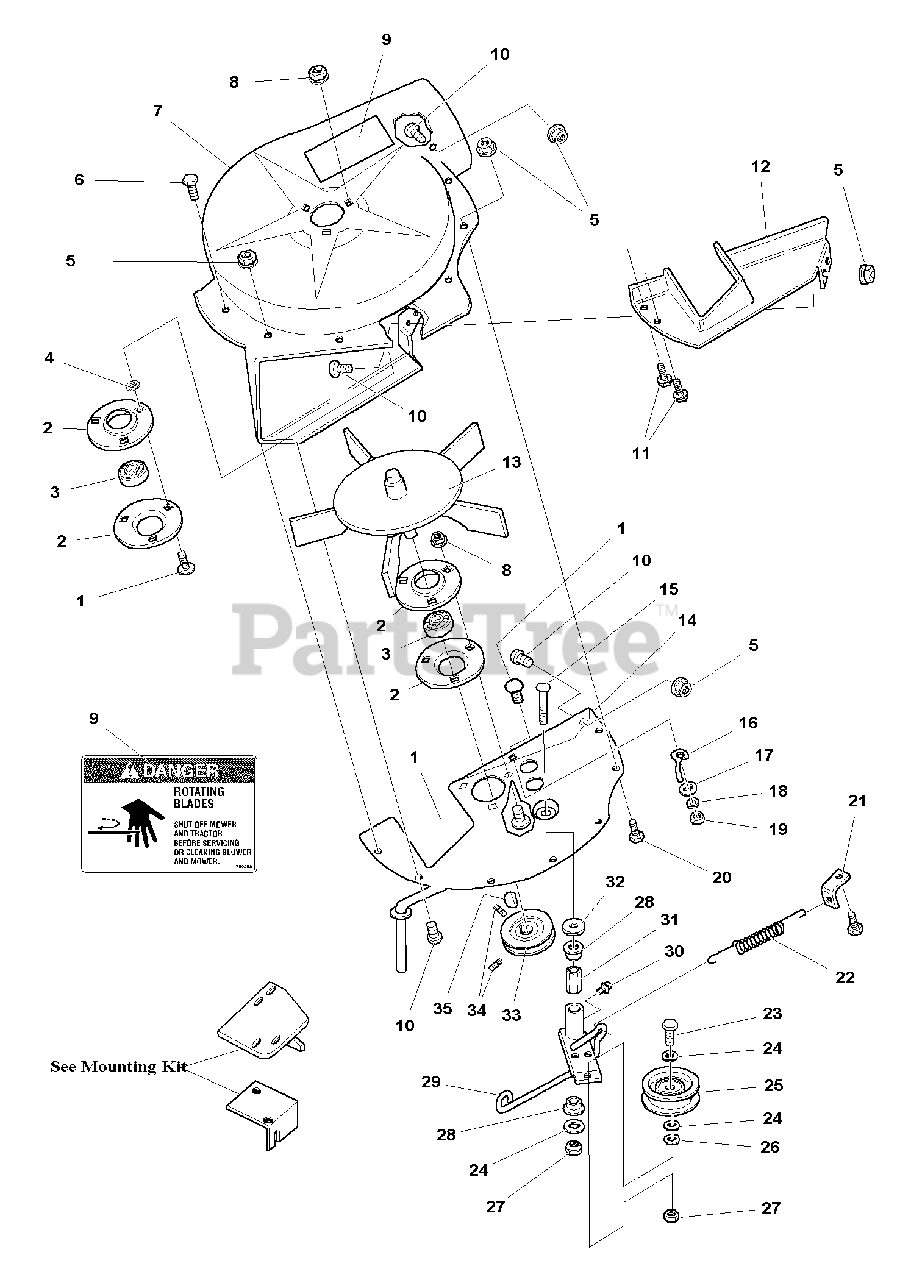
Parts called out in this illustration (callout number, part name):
1	CARRIAGE BOLT, 5/16-18 x 3/4
2	RETAINER, Bearing
4	PUSH NUT, 3/8
5	NUT, Hex, Flange Lock, 1/4-20
6	CAPSCREW, Hex, Taptite, 1/4-20 x 1/2
7	FAN HOUSING (Includes Decal, #9)
8	NUT, Flange, Whizlock, 5/16-18
9	DECAL, Danger, Blower
10	CARRIAGE BOLT, 1/4-20 x 3/4
11	SCREW, Wsh. Hd., 1/4-18 x 5/8
12	COVER, Bottom
13	FAN ASSY., 5 Blade
14	PLATE ASSY.
15	CARRIAGE BOLT, 3/8-16 x 2-1/4
17	WASHER, Flat
18	WASHER, Spring Lock, 5/16
19	NUT, Hex, 5/16
20	CAPSCREW, 1/4-20 x 5/8
21	BRACKET, Anchor, Spring
22	SPRING, Tension
23	CAPSCREW, Hex Hd., 3/8-16 x 1-1/4
24	WASHER, Plain
25	IDLER PULLEY ASSEMBLY, 2-3/4 OD
26	WASHER, Flat
27	NUT, Hex, Jam, Center Lock, 3/8-16
29	LEVER ASSY, Turbo (Incl. Ref. Nos. 30 &31)
30	FITTING, Grease
32	WASHER, Flat
33	PULLEY, Driven, 3 OD
34	SETSCREW, Hex, Socket Hd., 5/16-18 x 5/16
35	KEY, Woodruff, Modified
